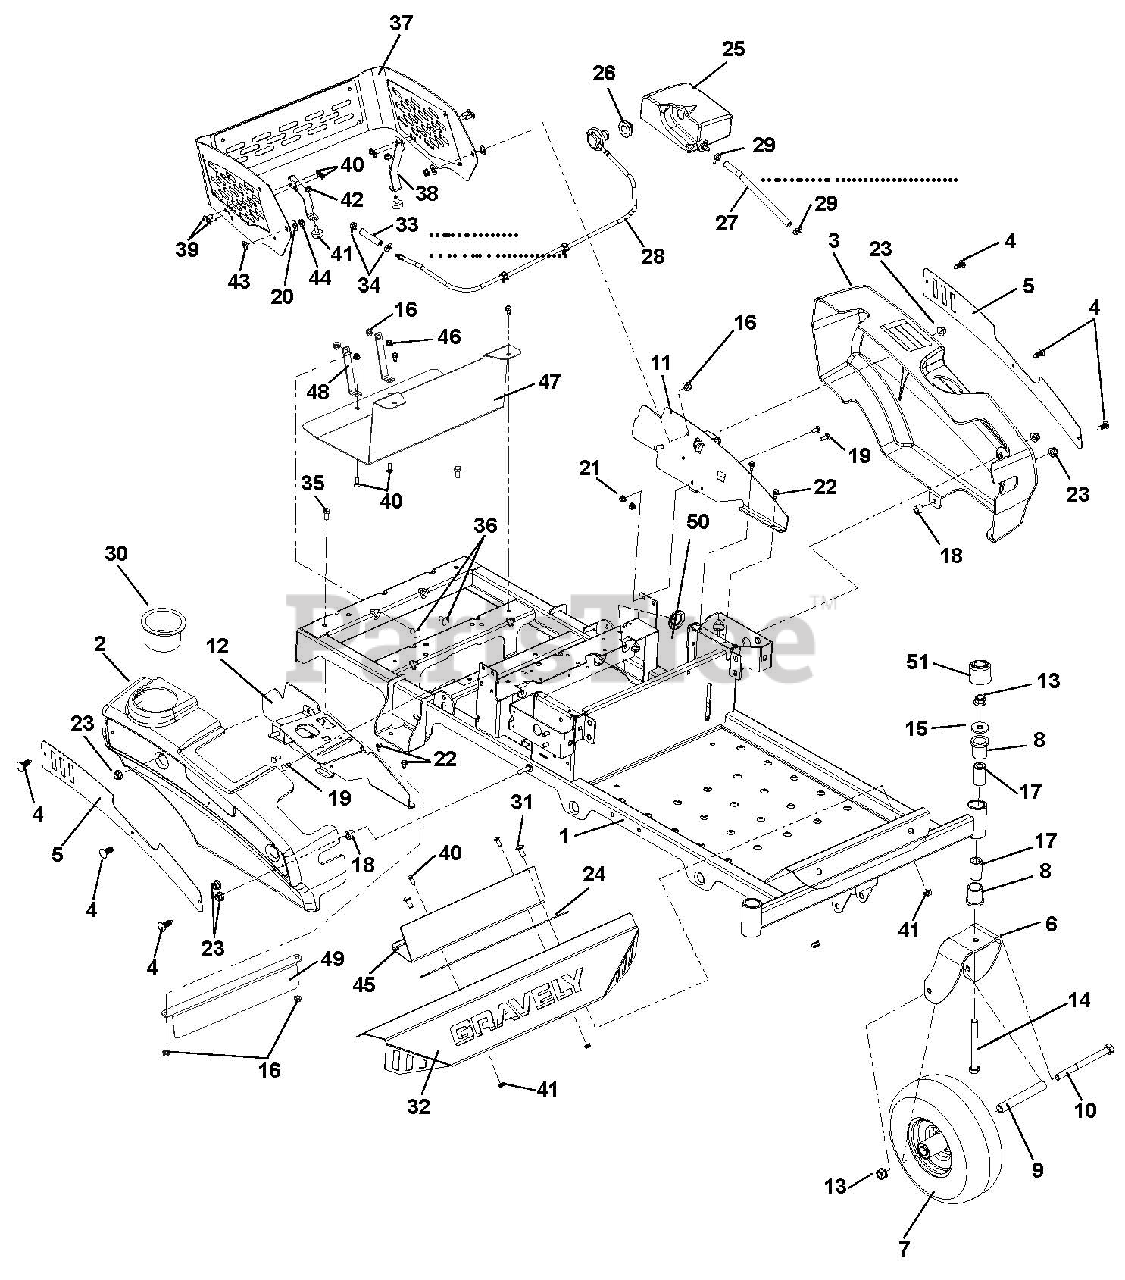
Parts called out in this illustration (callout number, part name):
1	Weldment, Frame
2	Fender, Right Hand
3	Fender, Left Hand
4	Rivet, Nylon
5	Plate, Fender
6	Fork, Caster
7	Wheel/Tire Assembly, 11 x 4-5
8	Bushing, Flange 1.00 x 1.25 x 1.50 x 1.50
9	Spacer, Wheel
10	Bolt, Hex .50-13 x 6.50
11	Weldment, Left Hand Fender Mount
12	Weldment, Right Hand Fender Mount
13	Nut, Locking Top Flange .50-13
14	Bolt, Hex .50-13 x 5.00
15	Washer, Flat Steel .511 x 1.441 x .125
16	Nut, Locking Top Flange .38-16
17	Spacer, Caster
18	Bushing, Sleeve .391 x .688 x .52
19	Bolt, Round Head Square Neck .25-20 x .75
20	Washer, Flat Nylon .52 x 1.00 x .08
21	Nut, Locking Top Flange .25-20
22	Screw, Tapping .25-20 x .50 Hex Washer Head Thread
23	Nut, Locking Nylon Flange .31-18
24	Grip, Adhesive, 1" x 16" BLK
25	Expansion Tank Subassembly
26	Grommet, Remote Vent Nitrile
27	Hose, .25 Low-Perm Bulk Gas, 7 inches
28	Assembly, Fuel Vent – Kohler, Briggs and Stratton
28	Assembly,Fuel Vent - Kawasaki
29	Clamp, Hose Wire .490/.510 x .116
30	Cupholder, Snap-In, 3.75 OD
31	Bolt, Round Head Square Neck .31-18 x .75
32	Foot Rest
33	Hose, .188 Low-PERM Bulk Gas
34	Clamp-Hose, Spring .188
35	Bolt, Hex .38-16 x 1.00
36	Bolt, Round Head Square Neck .38-16 x 1.00
37	Assembly, Engine Wrap
38	Bracket, Engine Wrap Foot
39	Bolt, Round Head Square Neck .25-20 x .50
40	Nut, Center Lock Flange .25-20
41	Bumper, Rubber
42	Nut, Serrated Flange .31-18
43	Bushing, Flange .325 x .499 x .3 x .875
44	Nut, Center Lock Flange .31-18
45	Plate, Back Foot Rest
46	Nut, Locking Top Flange .25-20
47	Guard, Heat Shield, ZT
48	Strap, Heat Shield, ZT
49	Guard, Hot Surface, ZT
50	Grommet, 1.0 I.D. x 1.38 O.D.
51	Cap, Dust
